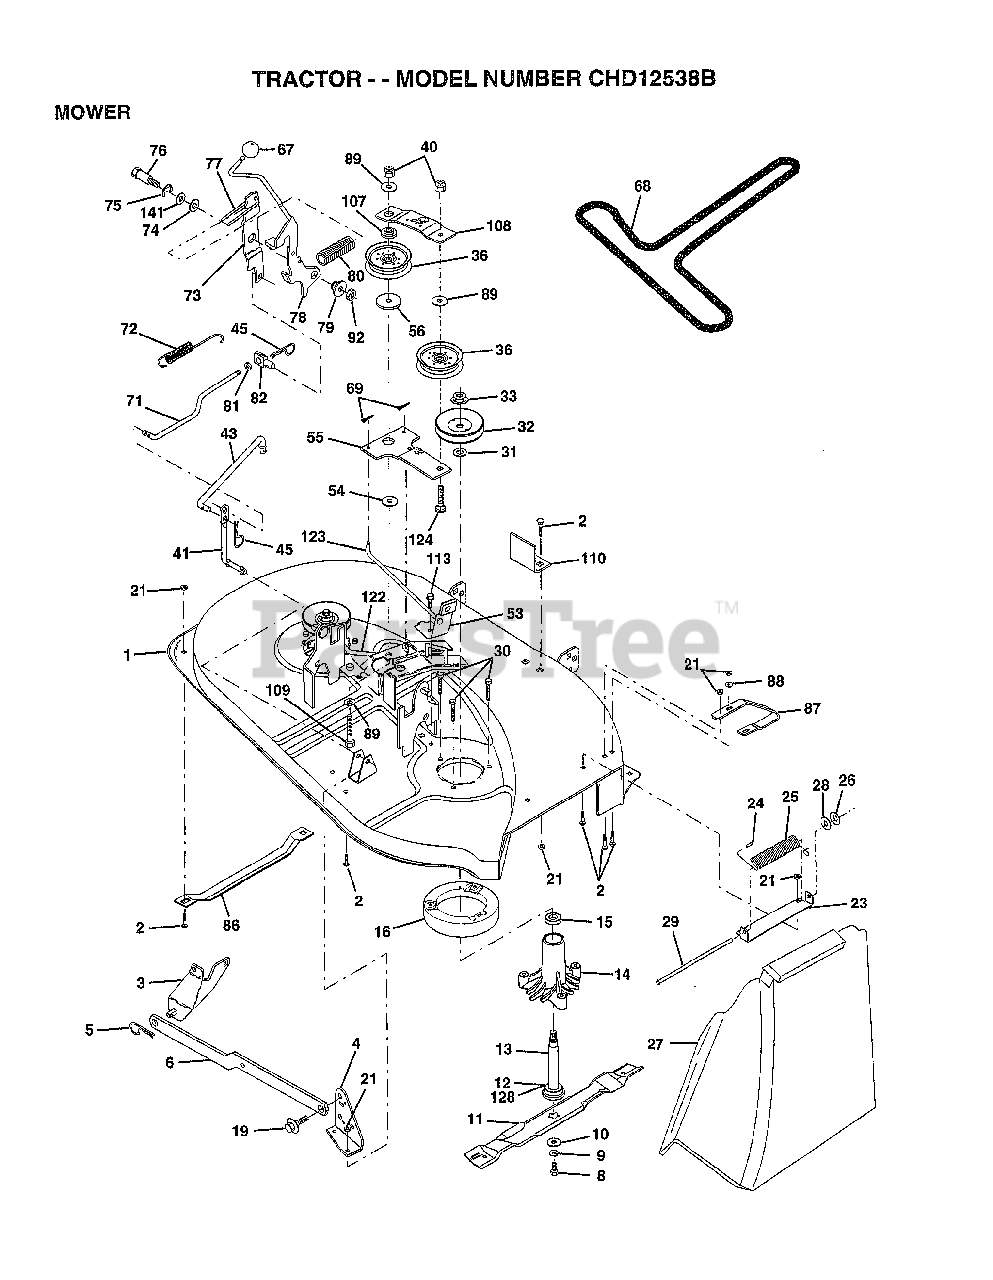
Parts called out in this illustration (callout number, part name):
2	BOLT
3	BRKT ASM SWAY BAR
4	BRKT DECK SW BAR
8	BLADE BOLT
10	WASHER.HARD.BLADE
11	"BLADE.38"" HIPERF"
12	BEARING.BALL
14	HSG ASM MANDREL
15	BEARING
16	STRIPPER RND MWR
19	BOLT SHD 5/16-18
23	BRKT DEFLECTOR
25	SPRING TORSION
27	DEFLECTOR-SHLD T
28	WASHER
29	ROD-HINGE T
30	"SCREW-THD ROLL,WA"
31	WASHER
32	PULLEY.MANDREL.38
36	FLAT IDLER PULLEY
41	PIVOT ROD
43	CLUTCH ROD SECOND
53	BRAKE ASM
54	HARDENED WASHER
55	IDLER ARM ASSY
56	SPACER RETAINER
67	KNOB.RD.7/16-14
68	BELT.V.T-PATH
71	ROD CLUTCH 38/42
72	RETURN SPRING
73	CLUTCH ARM SECOND
74	WASHER
75	RING
76	SHOULDER BOLT
77	SPRING KEEPER
78	LEVER.ASM.CLUTCH
79	BUSHING
80	SPRING.CLUTCH.MWR
81	NUT
82	TRUNION ADJ
86	RUNNER-LH M
87	RUNNER RH
88	WASHER M
89	WASHER GT
92	NUT
107	RETAINER SPACER
108	IDLER ARM STIFF
109	BOLT
110	UPSTOP DECK FT 38
113	SCREW
122	BRAKE ROD LH
123	BRAKE ROD RH
124	BOLT
128	WASHER.FELT.
141	WASHER .T
